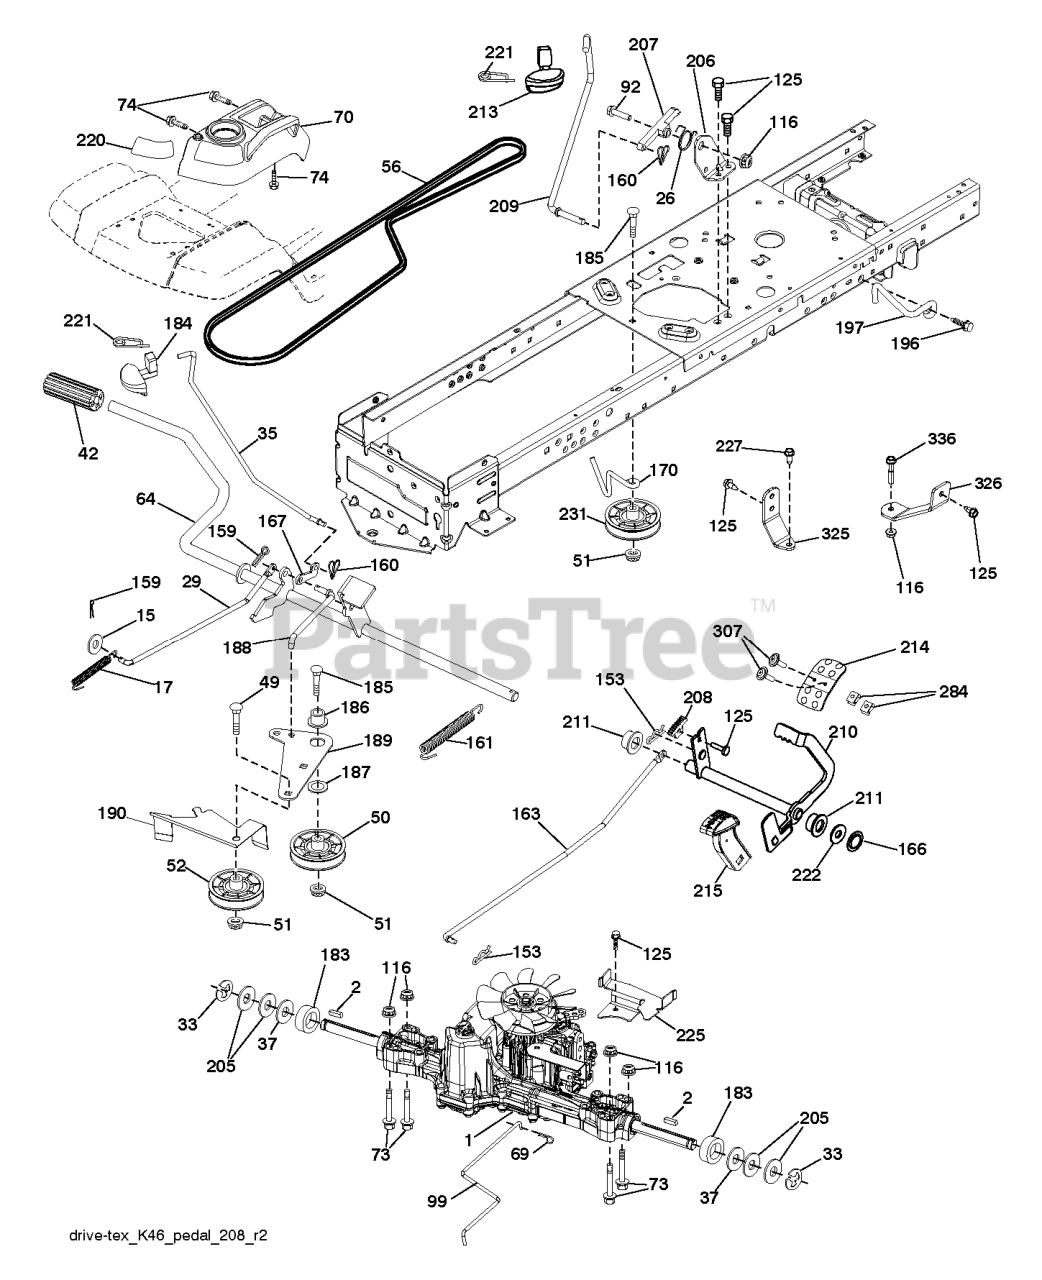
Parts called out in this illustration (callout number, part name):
2	SQUARE KEY
15	WASHER
17	SPRING.BRAKE.K46.GREEN
26	SPRING.RETURN.CRUISE
29	ROD.BRAKE.K46
35	ROD .BRAKE. PARKING. GT. HUSQ.
35	ROD ROD.PARKINGBRAKE.GT.HUSQ/P
37	WASHER.HARDENED
42	PEDAL COVER T
50	IDLER.FLAT.910.OFFSET
51	NUT LOCK FLG 3/8-16 UNC
52	IDLER.V-GROOVE.910.OFFSET
56	V-BELT.MOWER.92.40.42/K46
64	SHAFT.ASM.PEDAL.BRK.CNTR
69	HAIRPIN.SOFT.ZINC.059X1.125
70	CONSOLE.ASM.RH.GT.FC.HUSQ
74	SCREW.HI-LO.CONSOLE
92	BOLT
99	ARM.PIVOTING.TCRD.GEN2.5.BAGGE
99	ROD.SPRING.BYPASS.K46.LT.Z
116	NUT LOCK HEX FLANGE 5/16-18
125	SCREW
153	RETAINER M
159	COTTER PIN
160	RETAINER CLIP
161	SPRING, RETURN LT
163	ROD.CONTROL.K57R.K46
166	NUT.PUSH.625
167	LATCH.BRAKE.SPRING
170	KEEPER.CENTER SPAN.1.688
183	SPACER AXLE
184	HANDLE.PARKING.BRAKE.H (BLK)
186	SPACER.RETAINER
187	WASHER 12/32X2X10GA
188	LINK.CLUTCH.GROUND DRIVE.LONG
189	BELLCRANK.GROUND.DRIVE.TEX.
190	KEEPER.BELLCRANK.DRIVE
196	SCREW 3/8-16X1
197	BRKT.42.FCS.CLUTCH.ANTIROTATIO
206	BRACKET.MOUNT.CRUISE.LATCH
207	LATCH.CONTROL.CRUISE.TEX
208	GEAR.SECTOR.CONTROL.CR
209	ROD ROD.CRUISECONTROL.GT.HUSQ/
209	ROD.CONTROL.CRUISE.GT.
210	ROCKER.ASM.PEDAL.CONTR
211	BEARING.NYLON
213	KNOB.CONTROL.CRUSIE.HU
214	PEDAL.FORWARD.HUSQVARNA.DEALER
215	PEDAL.COVER.REVERSE.CRD.X428BK
220	REFLECTOR.RH.TEX GT
221	RETAINER.SPRING.CLIP.H
222	WASHER 21/32 X 1-1/4 X 10 GA.
225	KEEPER.BELT.TRANSAXLE.K46
227	SCREW.THDROL.5/16-18X3/4.TTY
231	IDLER.V-GROOVE.1.688.OFFSET
284	NUT.U-CHNL.1/4-20.550DP.350PNL
307	SCREW.MACHINE.CR.1/4-20
325	TORQUE.STRAP.K46.LT.LH
326	BRCKT.PNT.TRQ.STP.46.18TIRE.RH
336	BOLT.5/16-18X1-3/4.FLANGED.HEX
